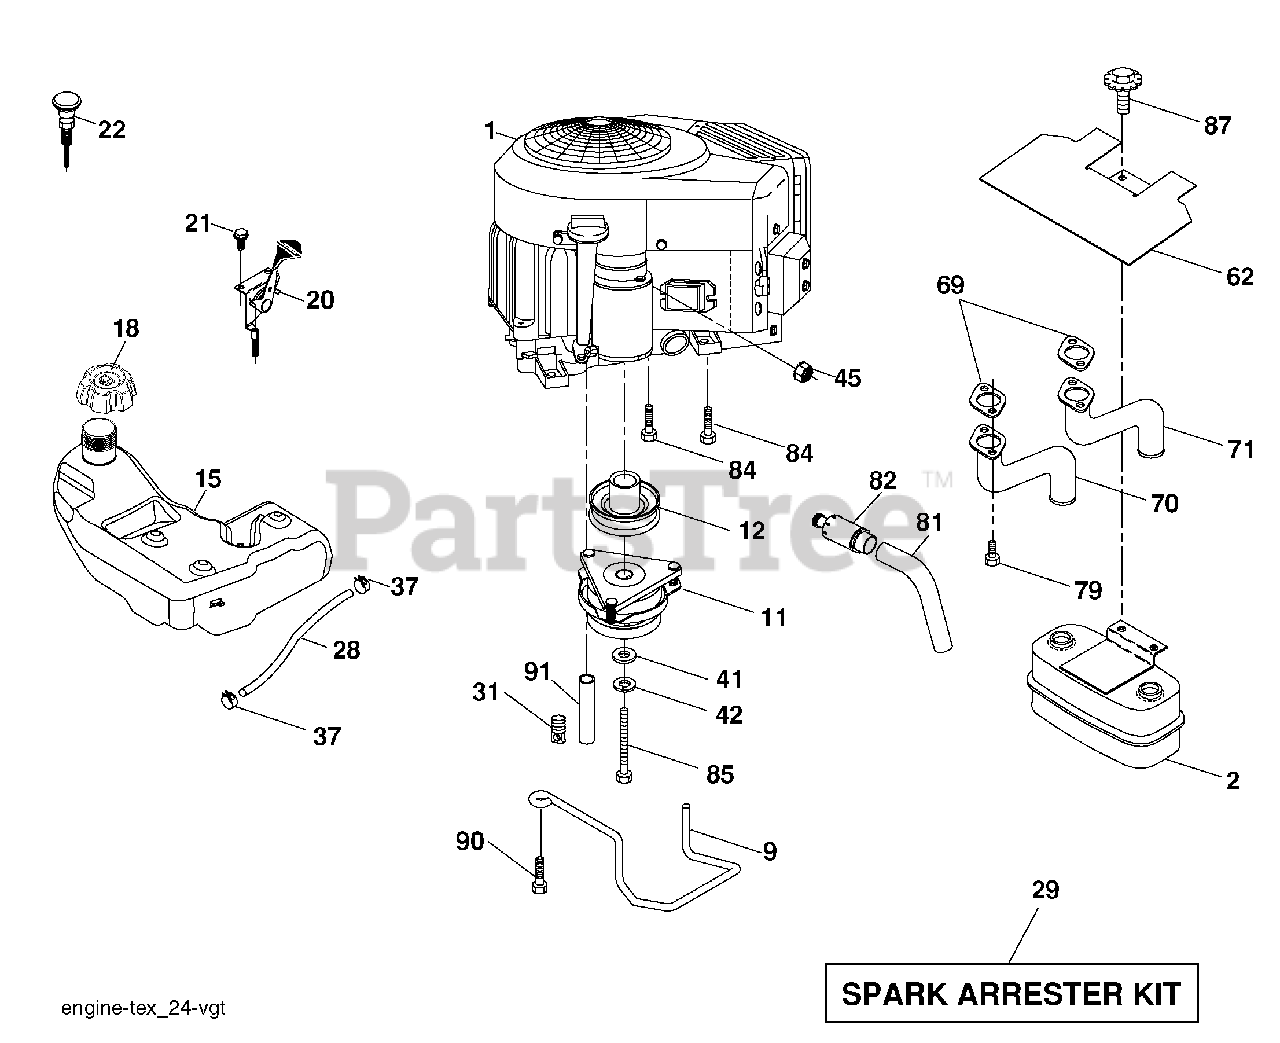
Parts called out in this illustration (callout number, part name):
2	Muffler
9	Keeper Asm. Belt Engine
11	Clutch Electric
12	Pulley Engine
15	Tank Fuel 4.0
18	Cap Asm
20	Control Throttle
21	Screw 10 x 3/4 Single Lead-Hex
22	Control Choke
28	Fuel Line
29	Spark Arrester Kit
31	Clip Push-In Hinged
37	Clamp Hose
41	Washer 1-1/2 OD x 15/32 ID x .250
42	Washer Lock 7/16
45	Nut Keps Hex 1/4-20 unc
62	Shield Heat Muffler
69	Gasket
70	Tube Exhaust LH
71	Tube Exhaust RH
79	Screw Socket Head
81	Tube Drain Oileasy
82	Plug Drain Oil
84	Screw 3/8-16 x 1-1/4
85	Bolt Hex 7/16-20 x 3.75 Gr. 5
87	Bolt 5/16-18 unc x 1 w/Sems
90	Screw 3/8-16 x 1
91	Bushing
